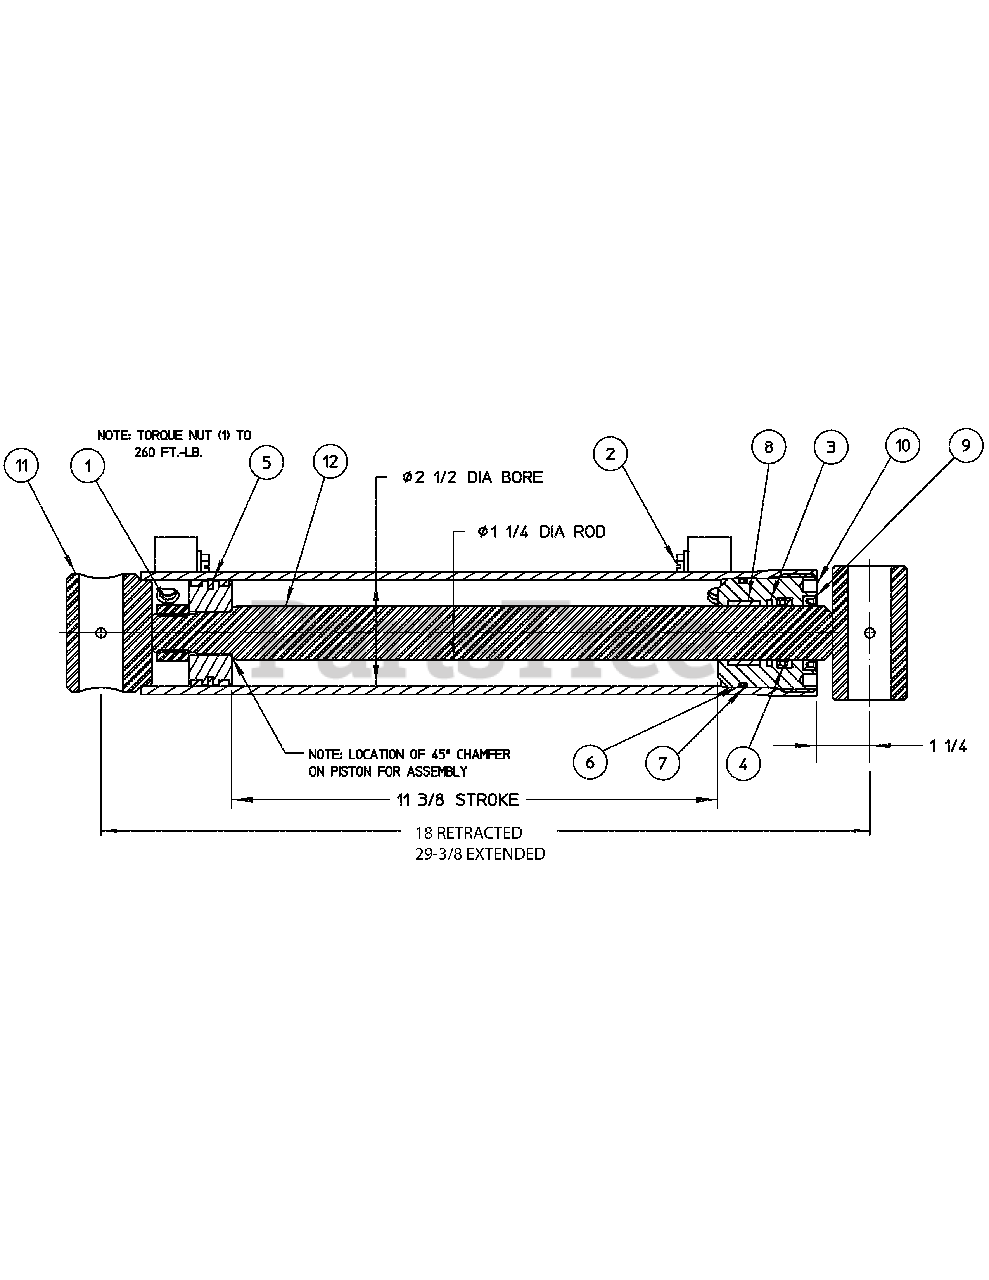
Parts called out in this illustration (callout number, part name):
1	Nut, 7/8 NF Nylok
2	Cap Plug, 9/16-18 Th’d with O-Ring
3	Step Seal*
4	U-Cup Seal*
5	Piston Assembly
6	O-Ring*
7	Back-Up Ring*
8	Wear Ring*
9	Wiper Seal*
10	Gland*
11	Cylinder Tube Weldment
12	Piston Rod Weldment
